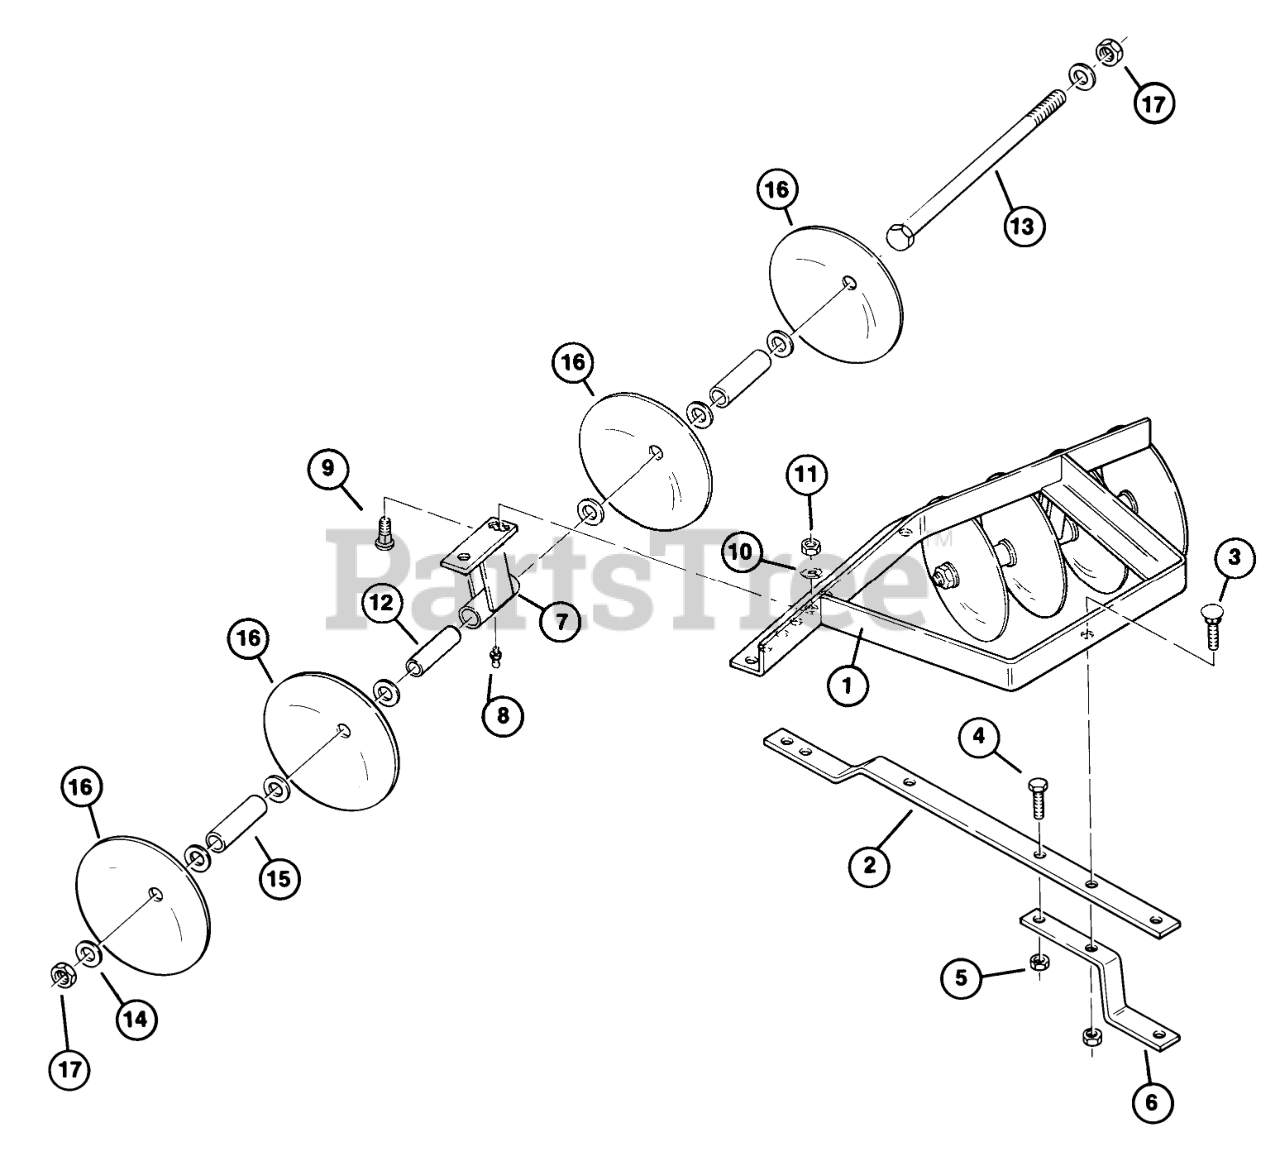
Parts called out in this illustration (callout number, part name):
1	Frame Assembly
2	Hitch Bar
3	CARRIAGE BOLT -4
4	Hhcs
5	Eslok Nut
6	Coupler Adapter
7	Bearing Hanger Assembly
8	Grease Fitting
9	Bolt
10	LOCKWASHER
11	Nut
12	Bearing
13	Bolt 3/4-10 X 16
14	Washer
15	Tube
16	BLADE DISC
